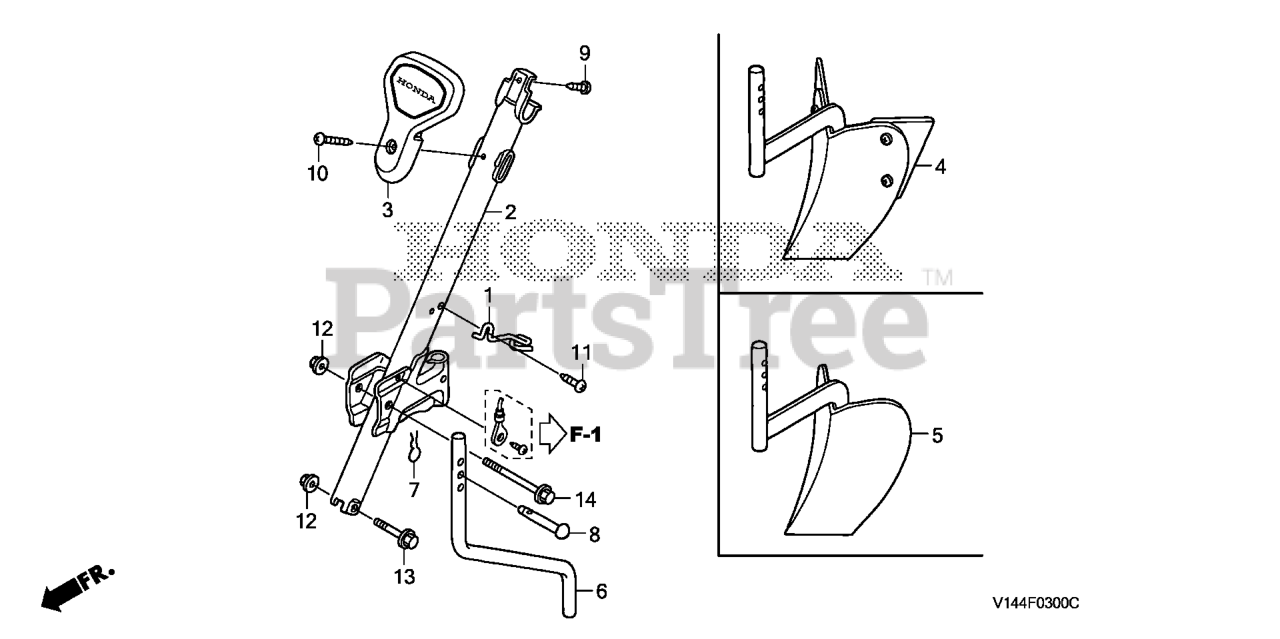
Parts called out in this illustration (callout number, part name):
1	GUIDE, CABLE
2	HOLDER, COLUMN
3	COVER, HANDLE
4	RIDGER ASSY., WIDE
5	RIDGER
7	PIN, SNAP (7MM)
8	PIN (7X48)
9	SCREW, TAPPING (5X16)
10	SCREW, TAPPING (5X25)
11	SCREW, TAPPING (5X16)
12	NUT, FLANGE (8MM)
13	BOLT, FLANGE (8X45)
14	BOLT, FLANGE (8X85)
